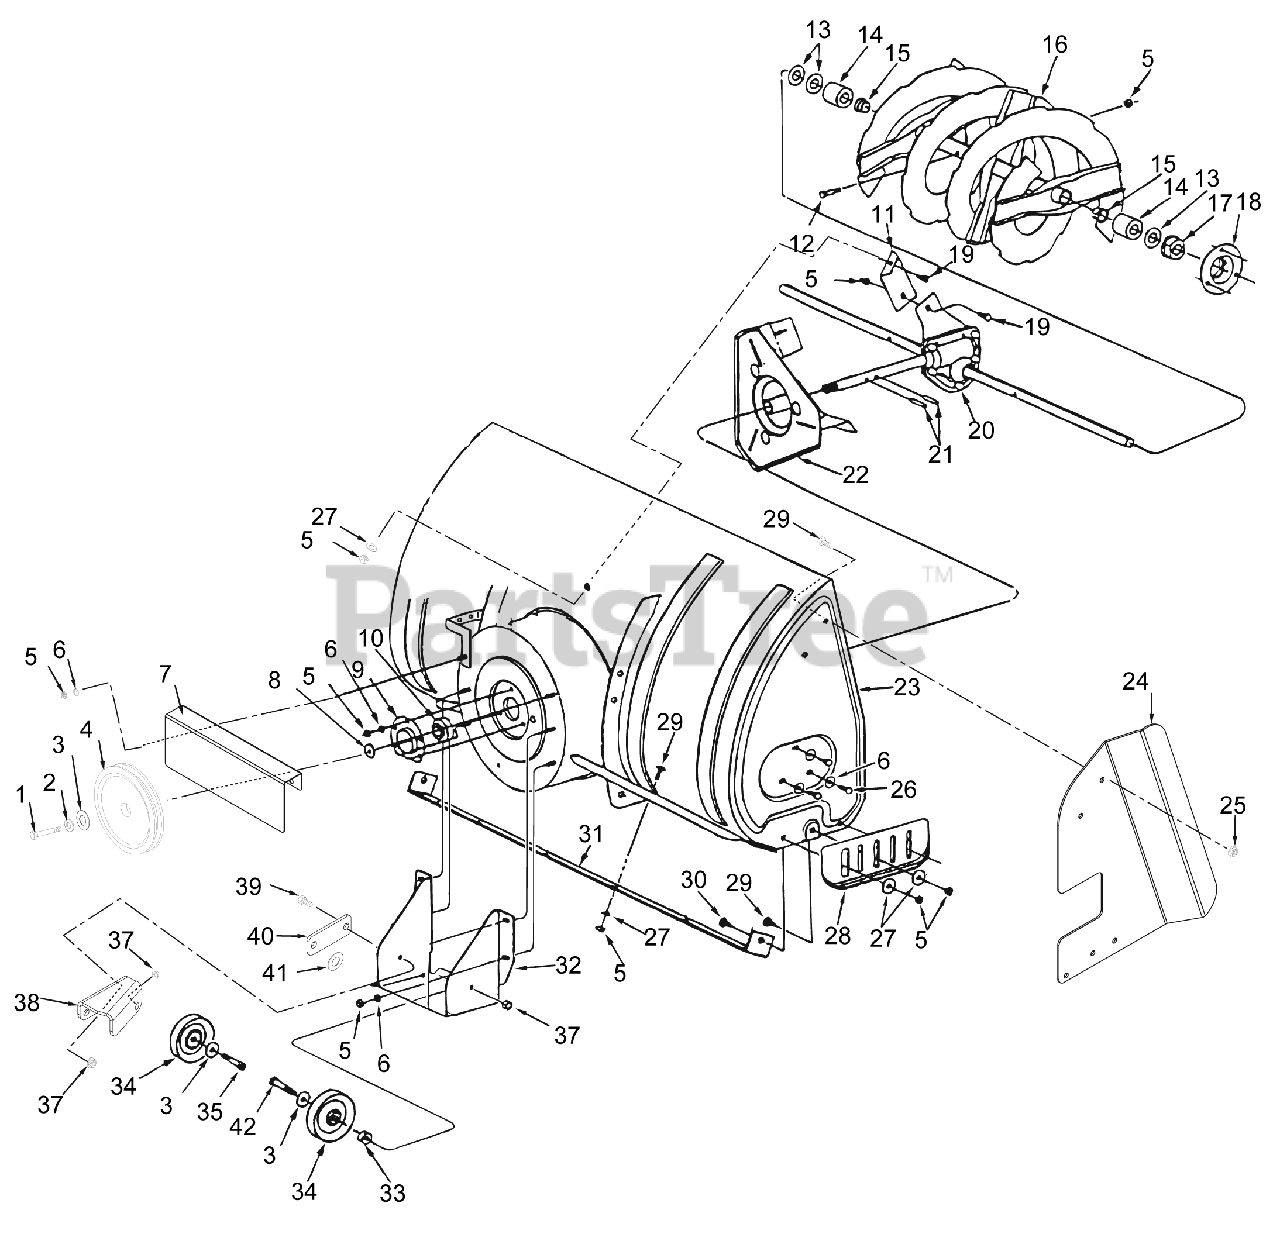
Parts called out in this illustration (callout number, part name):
1	BLT-HEX .38-24X1.0 YWZC GR5
2	@WSHR-LK .38X.094 REG YWZC
3	@WSHR-FL-STL.406X.812X.065 YWZ
4	Pulley, V-Type
5	@NUT-LK-CTR .31-18 YWZC
6	@WSHR-LK .31X.078 REG YWZC
7	GUARD,FINGER
8	Bushing
9	Housing, Bearing
10	Bearing, Ball
11	Bracket, Housing Brace
16	Spiral Assembly, R.H.
17	Bearing Flange
18	Housing, Bearing
19	@BLT-HEX .31-18X.75 GR5 YWZC
20	Gear Assembly
22	Impeller Assembly
23	Housing Assembly
24	DRIFT-CUTTER RH
25	@NUT-LK-TOP-FLG .31-18 YWZC
26	@SCR-TAP .31-18X.75 HWH TR YWZ
27	@WSHR-FL-STL.344X.688X.065YWZC
28	Skid Shoe
29	@BLT-RDHDSQNK .31-18X.75 G5YZ
30	@BLT-RDHDSQNK .31-18X1.00 G5YZ
31	Scraper Plate
32	Bracket, Idler
33	BSHG-SLV .391X.688X.52 PM
34	IDLER-V 4.00 X .38 NWHAMSHR
35	@BLT-HEX .38-16X1.50 GR5 YWZC
36	Spacer
37	@NUT-LK-TOP-FLG .38-16 YWZC
38	BKT,IDLER SHEAVE
39	@BLT-HEX .38-16X1.00 GR5 YWZC
40	PLATE,SHIM
41	WSHR-FL-STL .406X1.00X.188 YWZ
42	@BLT-HEX .38-16X2.00 GR5 YWZC
